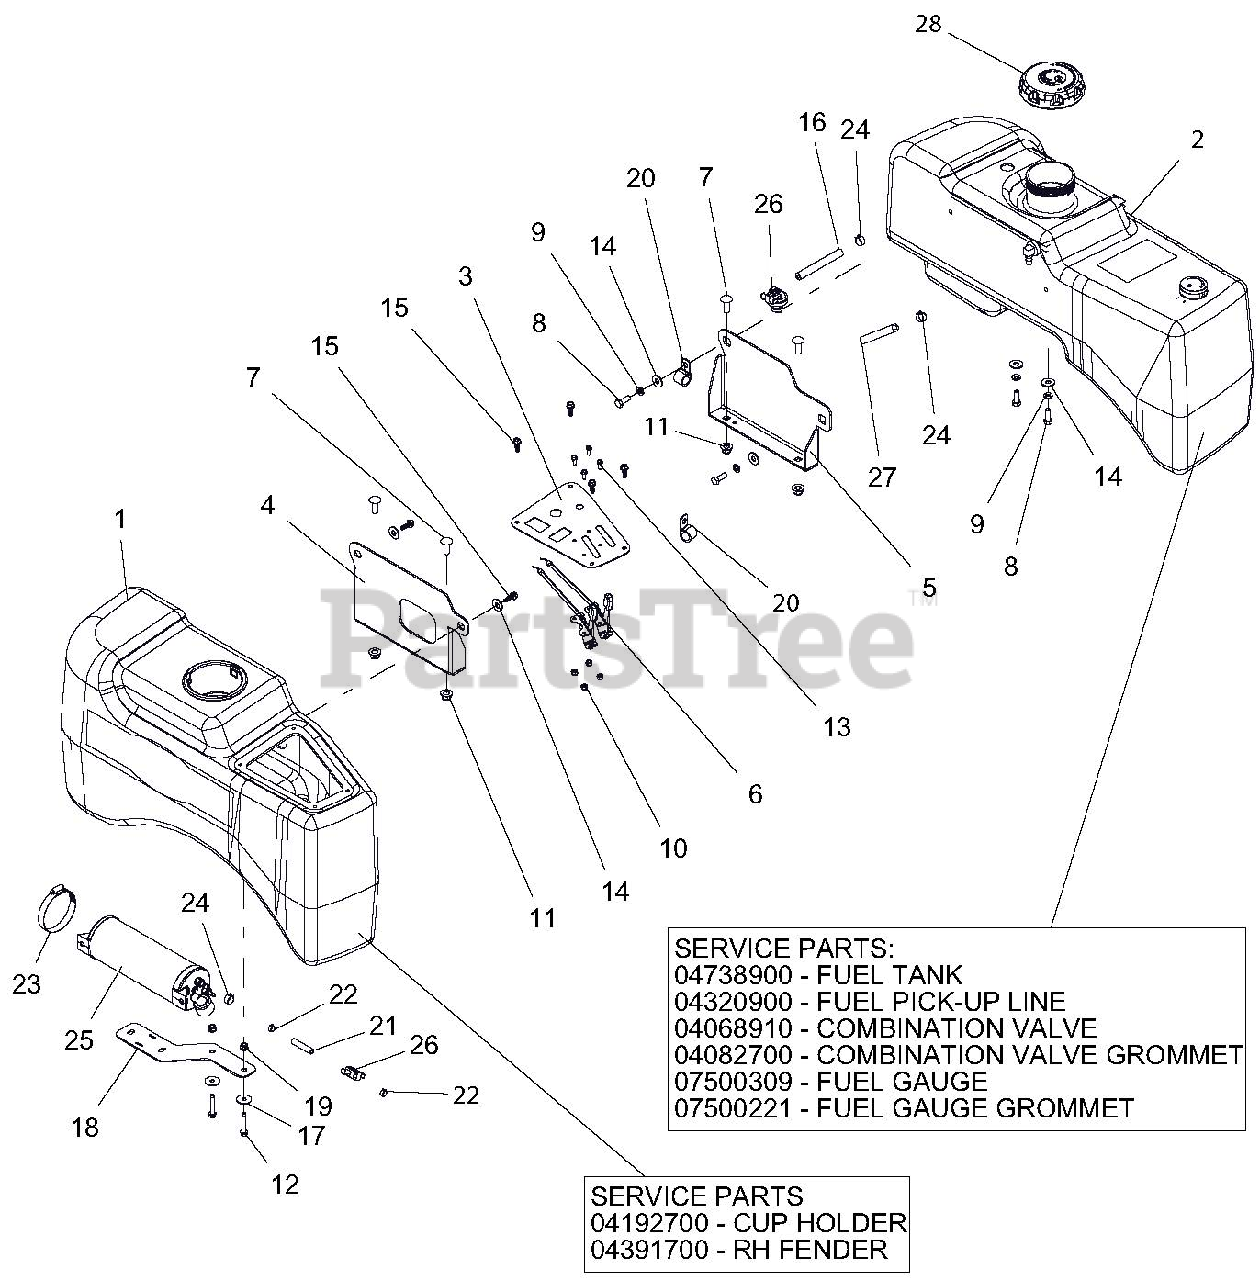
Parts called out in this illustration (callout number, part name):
1	ASM, FENDER W/CUPHOLDER
1	CUP HOLDER
1	RH FENDER
2	HD, FUEL TANK ASSEMBLY
2	FUEL TANK
2	FUEL PICK-UP LINE
2	COMBINATION VALVE
2	COMBINATION VALVE GROMMET
2	FUEL GAUGE
2	FUEL GAUGE GROMMET
3	PANEL, INSTRUMENT-BLACK
4	BRKT, RH HD FUEL TANK MTG-RED
5	BRKT, LH HD FUEL TANK MTG-RED
6	CABLE, CONTROL
7	BLT-RDHDSHSQNK.38-16X1.0 G5YZ
8	BLT-HEX .31-18X.875 GR5 YWZC
9	WSHR-LK .31X.078 REG YWZC
10	NUT-LK-NYL #10-24 YWZC
11	NUT-LK-NYL-FLG .38-16 YWZC
12	SCR-TAP .25-20X1.50 HWH TR YZ
13	@SCR-MCH 10-24X.50 HWH YCWZ
14	WSHR-FL-STL.38X.875X.083 YWZC
15	SCR-PLASTITE .25-10X.75 YWZC
16	.25 LOW-PERM GAS HOSE 40.00" LG - TANK TO CARB CANISTER
17	WSHR-FL-STL .281X1.000X.063 YWZC
18	PLATE, CANISTER MTG-BLACK
19	NUT-LK-NYL-FLG .25-20 YWZC
20	CLAMP, CUSHIONED STE5EL .7
21	.188 ID LOW-PERM X 52.0 LG - CARBON CANISTER TO ENGINE
22	CLAMP - HOSE, SPRING .188
23	CLAMP, HOSE 2.32/3.
24	CLAMP, FUEL LINE
25	CANISTER, CARBON 9.3 GAL
26	CLIP, T, .38-.50
27	.25 LOW-PERM GAS HOSE 18.50" LG - TANK TO ENGINE
28	CAP, NON NONVENT AUTOLOCK
